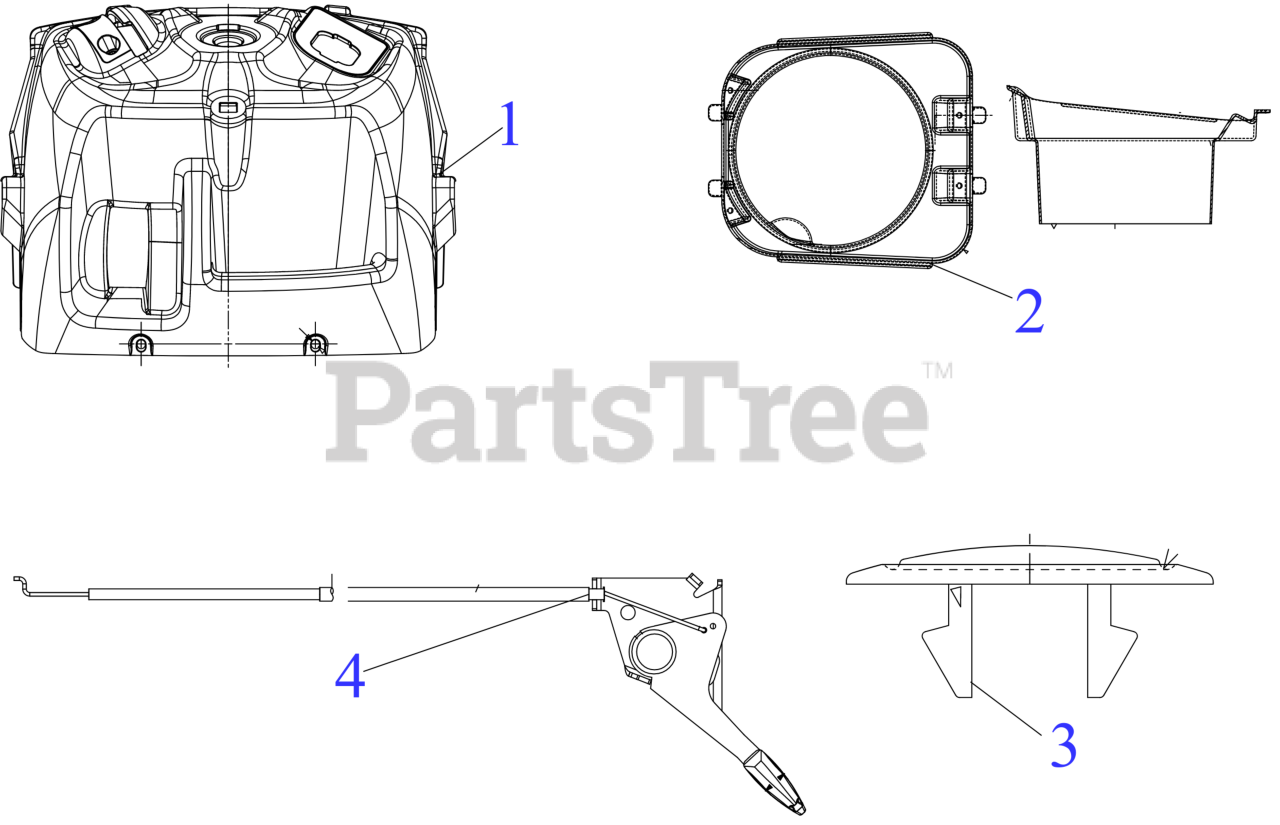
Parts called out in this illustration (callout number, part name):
1	UPPER DASH
2	HOOD PLENUM
3	CHOKE PLUG
4	THROTTLE CABLE 28" x 1.1
